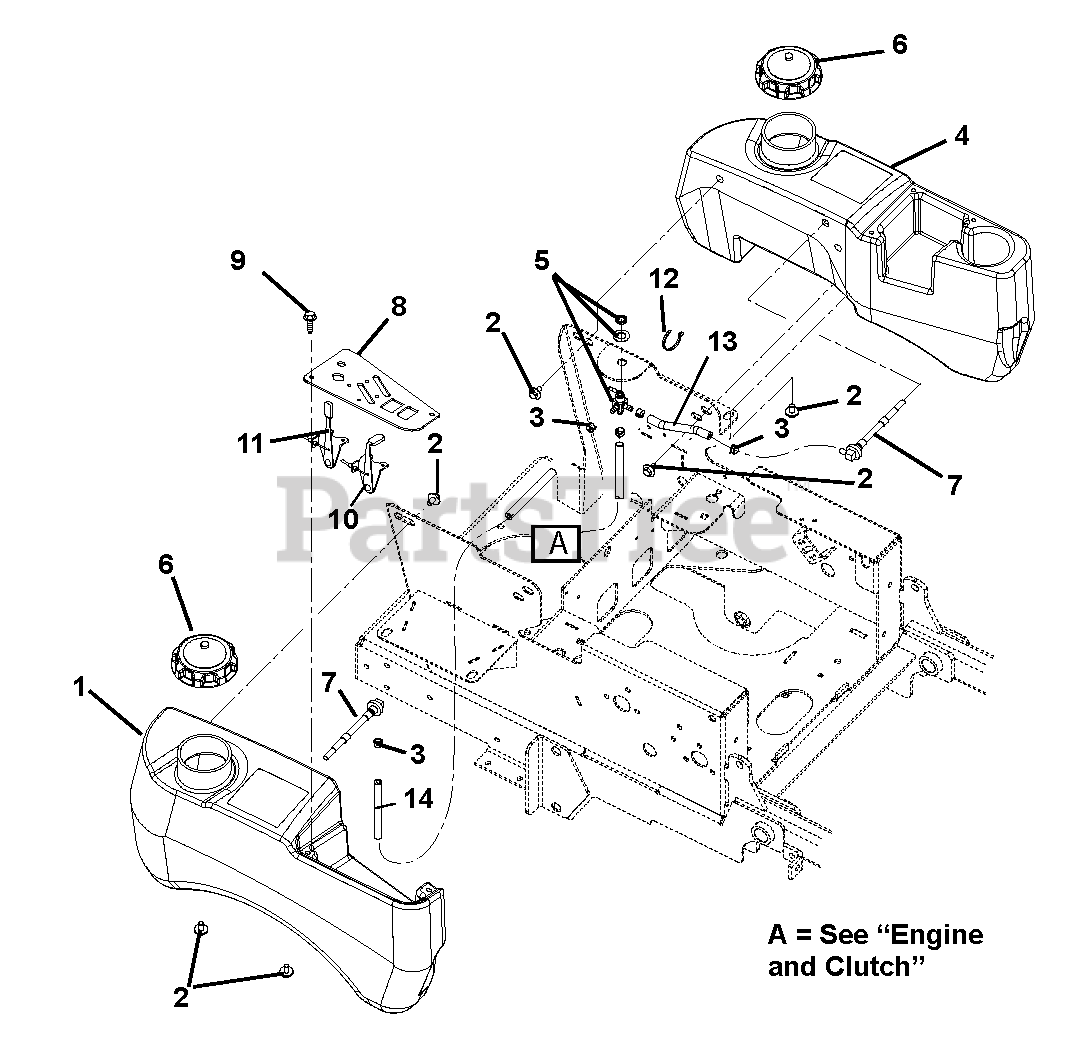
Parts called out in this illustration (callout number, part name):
1	Tank, Gas- Right Hand (SN 000200 - 000799)
2	Bolt, SEMS .31-18 x .62
3	Clamp, Fuel Line
4	Tank, Left Hand Fuel (Eye-Q) (SN 000200 - 000799)
5	Valve, Fuel
6	Cap, Fuel
7	Kit, 16.5" Fuel Line-Compact (SN 000200 - 000799)
8	Panel, Control
9	Screw, Machine 10-24 x .50
10	Cable, Throttle (SN 000200 - 000799)
11	Cable, Choke
12	Cable Tie
13	Hose, .25 Low-PERM Bulk Gas (SN 000200 - 000799)
14	Hose, .25 Low-PERM Bulk Gas
